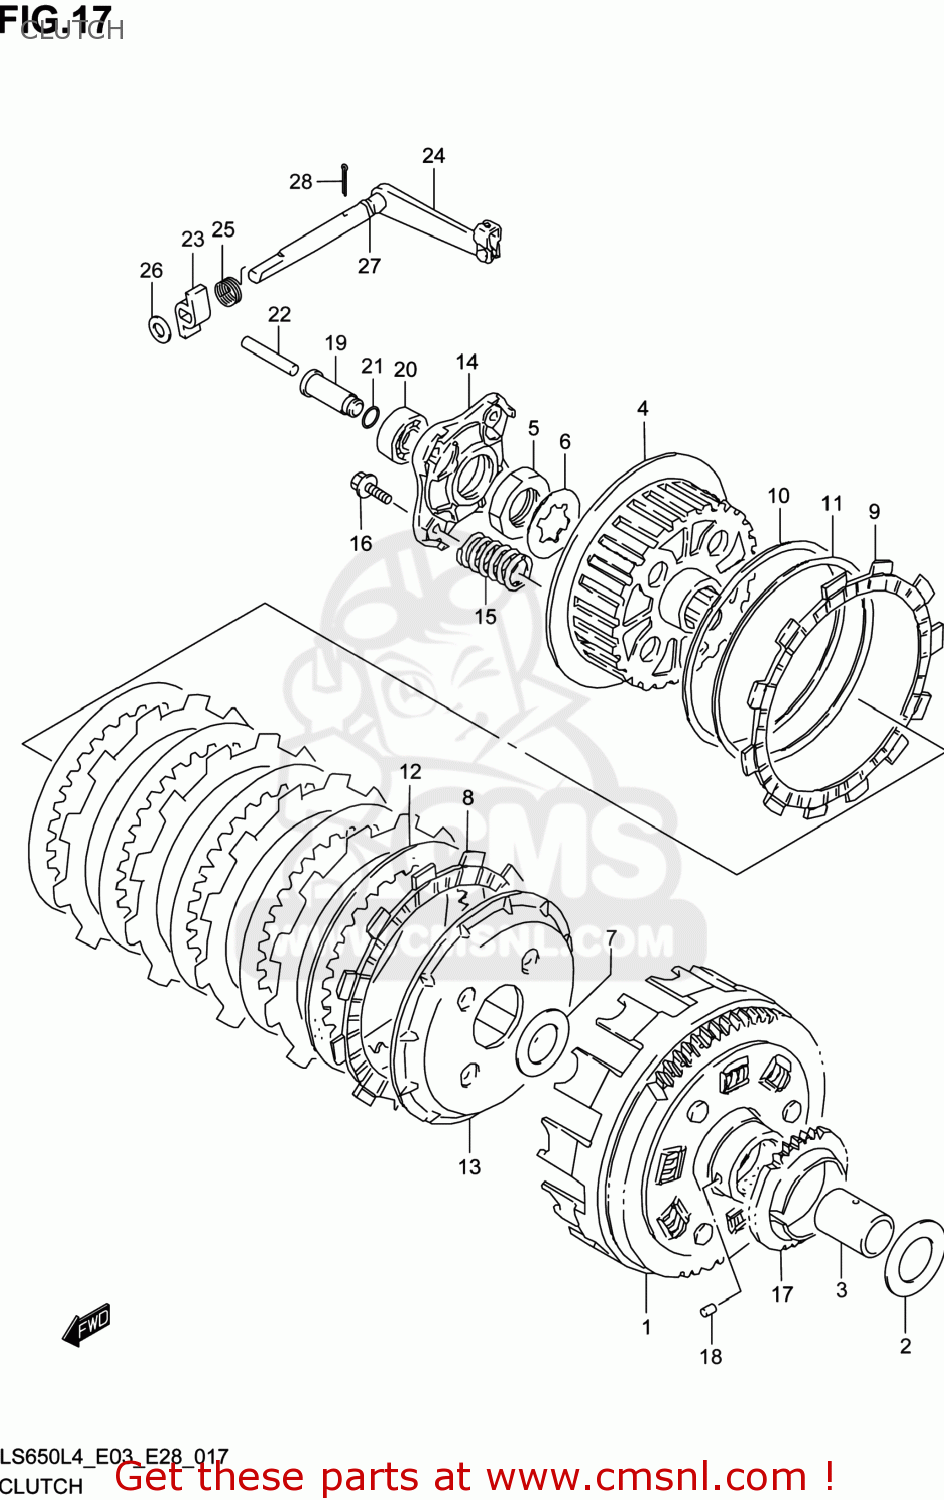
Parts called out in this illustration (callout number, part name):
1	GEAR ASSY,PRI DRIVEN
2	WASHER
3	SPACER(22X28X32.5)
4	HUB,CLUTCH SLEEVE
5	NUT
6	WASHER,LOCK
7	WASHER
8	PLATE,CLUTCH DRIVE (NAS)
9	PLATE,CLUTCH DRIVE(T:3.5) (NAS)
10	SEAT,WAVE WASHER(T:1.4)
11	WASHER
12	PLATE,CLUTCH DRIVEN(T:1.6) (NAS)
13	DISC,CLUTCH PRESSURE
14	PLATE,RELEASE
15	SPRING
16	BOLT
17	GEAR,ENG OIL PUMP DRIVE
18	PIN(6X6)
19	PIECE,CLUTCH PUSH
20	BEARING(12X28X8)
21	O RING(D:1.9,ID:8.6)
22	ROD,CLUTCH PUSH
23	CAM,CLUTCH RELEASE
24	ARM ASSY,CLUTCH RELEASE
25	SPRING
26	SHIM(10X14X1)
27	O RING(D:1.9,ID:6.8)
28	PIN
